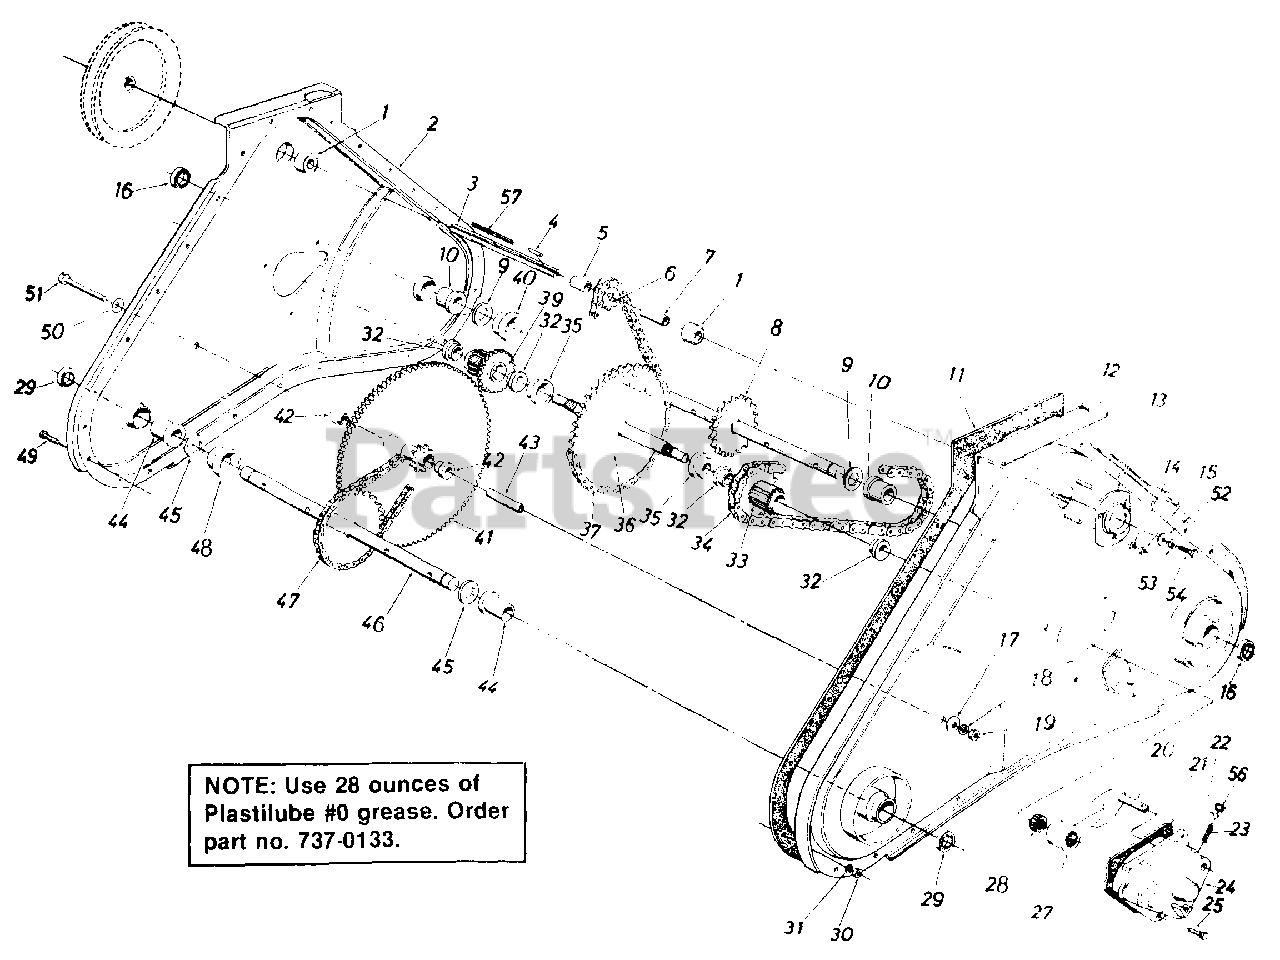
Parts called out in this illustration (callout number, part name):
1	Ball Bearing .62" I.D. x 1.38" O.D. x .44
2	Chain Case R.H. Half
3	Input Shaft .62" Dia.
4	Sq. Key 3/16" x 3/16" x .75" Lg.
5	Spacer .637" I.D. x .781" O.D. x .85" Lg.
6	Sprocket 9 Tooth x .62" Shaft
7	Spacer .637" I.D. x .781" O.D. x 1.44" Lg.
8	Tine Shaft Ass'y.
9	Fl-Wash. 1.28" I.D. x 1.62" O.D.
10	Flange Bearing 1.25" I.D.
11	Gasket - Housing
12	Chain Case L.H. Half
13	Bearing Housing 1-3/8" O.D.
14	L-Wash. 1/4" I.D.
15	Hex Nut 1/4-28 Thd.
16	Seal 1.25" I.D.
17	Belleville Wash.
18	L-Wash. 3/8" I.D.
19	Hex Cent. L-Nut 3/8-24 Thd.
20	Shift Yoke Ass'y. - L.H.
21	Gasket - Shift Housing
22	Ball Detent .250 Dia.
23	Compression Spring
24	Shift Housing - L.H.
25	Hex Tap-Tite 5/16-18 x .75" Lg.
27	Clutch Dog
28	Clutch Dog Driver
29	Seal 1.0" I.D. x 1.38" O.D.
30	Hex Nut 1/4-28 Thd.
31	L-Wash. 1/4" I.D.
32	Flange Brg. 1.00" I.D.
33	Sprocket Brg. Sleeve Ass'y.
34	#50 Chain - 5/8" Pitch x 50 Links - Endless
35	Stepped Spacer 1.0" I.D. x 1.75" O.D.
36	Clutch Shaft Ass'y.
37	#420 Chain 1/2" Pitch x 58 Links - Endless
39	Gear Bearing - Sleeve Ass'y.
40	Spacer 1.25" I.D. x 2.0" O.D. x .68" Lg.
41	Sprocket and Gear Ass'y.
42	Flange Brg. .628" I.D. x .753" O.D.
43	Hub Sleeve .38" I.D. x .625" O.D.
44	Flange Brg. 1.00" I.D. x 1.188" O.D.
45	Fl-Wash. 1.0" I.D. x 1.62" O.D.
46	Axle Shaft Ass'y.
47	#420 Chain 1/2" Pitch 46 Links - Endless
48	Spacer 1.0" I.D. x 2.0" O.D.
49	Hex Bolt 1/4-28 x .62" Lg.
50	Belleville Wash.
51	Hex Bolt 3/8-24 x 2.75" Lg.
52	Fl-Wash. 5/16" I.D.
53	L-Wash. 5/16" I.D.
54	Hex L-Bolt 5/16-24 x .75" Lg.
56	Cap Plug .250" Dia.
57	Sq. Key 3/16" x 2.0" Lg.
